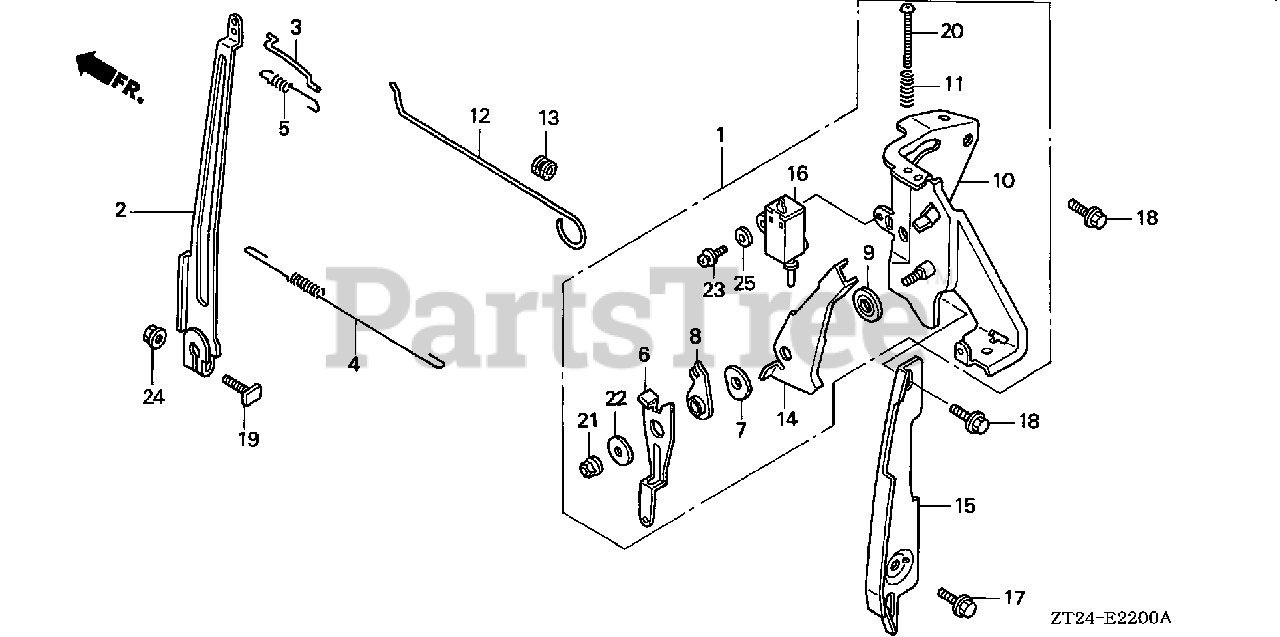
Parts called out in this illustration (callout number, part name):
1	CONTROL ASSY.
2	ARM, GOVERNOR
3	ROD, GOVERNOR
4	SPRING, GOVERNOR
5	SPRING, THROTTLE RETURN
6	LEVER, CONTROL
7	SPRING, LEVER
8	WASHER, CONTROL LEVER
9	SPACER, CONTROL LEVER
10	BASE, CONTROL
11	SPRING, CONTROL ADJUSTING
12	ROD, CHOKE CONTROL
13	GROMMET, CHOKE ROD
14	LEVER, STOP
15	PLATE, SIDE
16	SWITCH ASSY., ENGINE STOP (N.O)
17	BOLT, FLANGE (6X12) (CT200)
18	BOLT, FLANGE (6X14) (CT200)
19	BOLT, GOVERNOR ARM
20	SCREW, ADJUSTING
21	NUT, SELF-LOCK (6MM)
22	WASHER, WHEEL (6MM)
23	SCREW-WASHER (4X12)
24	NUT, FLANGE (6MM)
25	WASHER, PLAIN (4MM)
